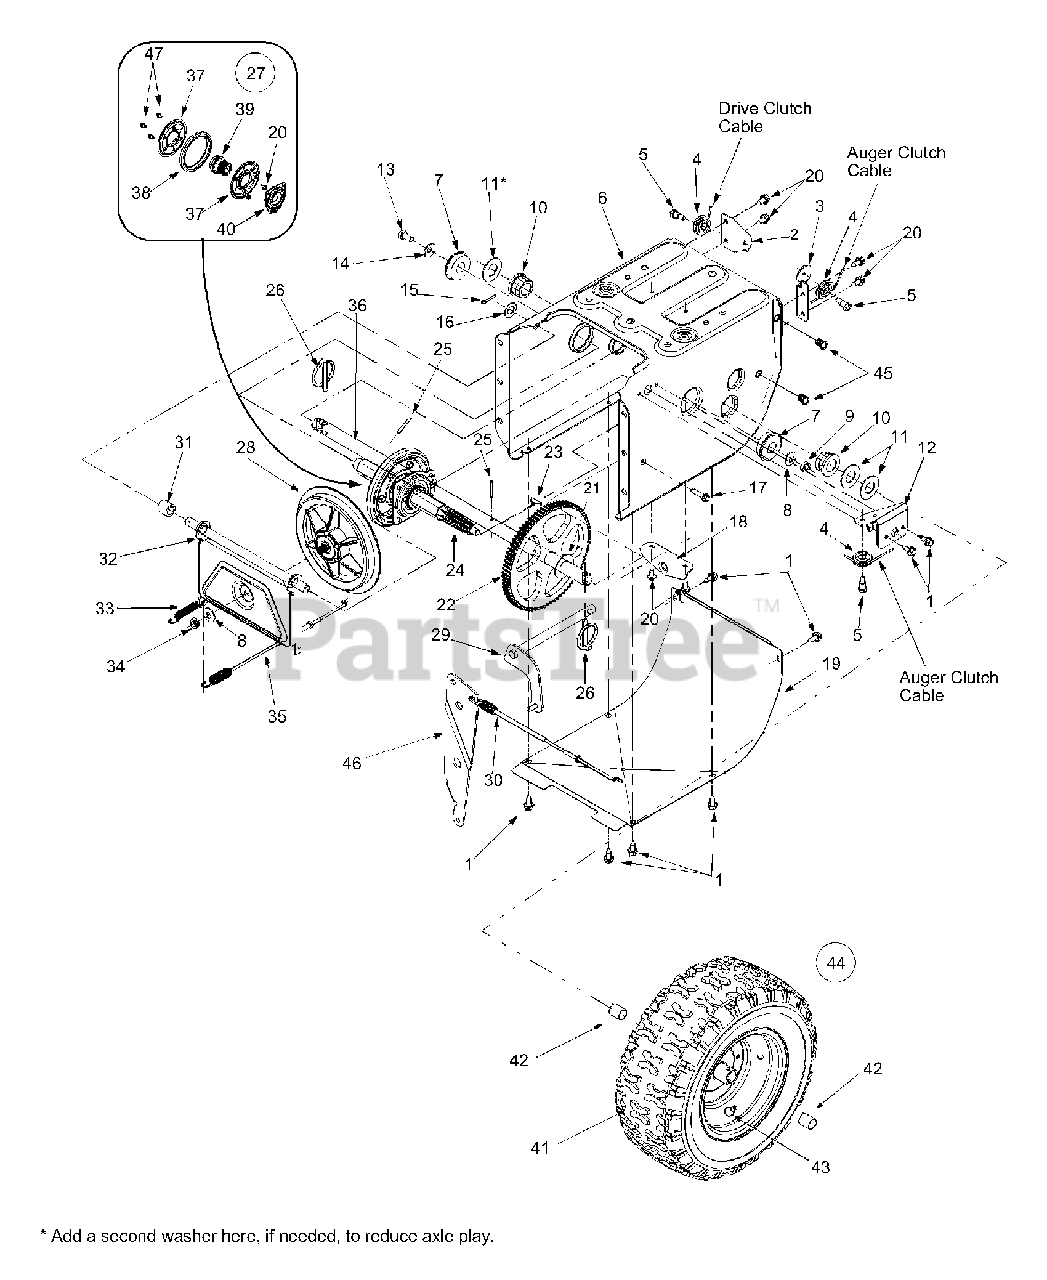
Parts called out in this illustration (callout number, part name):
1	Hex Screw 1/4-20 x .625
5	Shoulder Screw 1/4-28 x .375
8	Bell Washer
9	Lock Jam Nut, 3/8-24
10	Hex Flange Bearing
11	Flat Washer, .76 x 1.49 x .06
14	Bell Washer .340 ID x .872 OD
15	Cotter Pin, .125 x .75
16	Flat Washer .536 ID x .930 OD
17	Hex Washer Screw 1/4-20
21	Flat Washer .760 ID x .50 OD
22	Gear, 80-tooth
23	Key, 3/16 x 3/4
24	7-Tooth Shaft
25	Roll Pin
26	Clik Pin
27	Friction Wheel Assembly
28	Friction Wheel Disc
29	Wheel Shift Rod Assembly
30	Drive Cable, Auger
31	Spacer
34	Jam Nut, 3/8-24
35	Drive Cable, Clutch
36	Wheel Axle, .750 x 22.21
37	Friction Wheel Side Plate
38	Friction Wheel Rubber
39	Friction Wheel Hub
40	Friction Wheel Bearing
41	Tire Only, 16 x 6.5 x 8
42	Sleeve Bearing, .75 x .87 x 1
43	Air Valve
47	Hex Washer Screw 1/4-20
